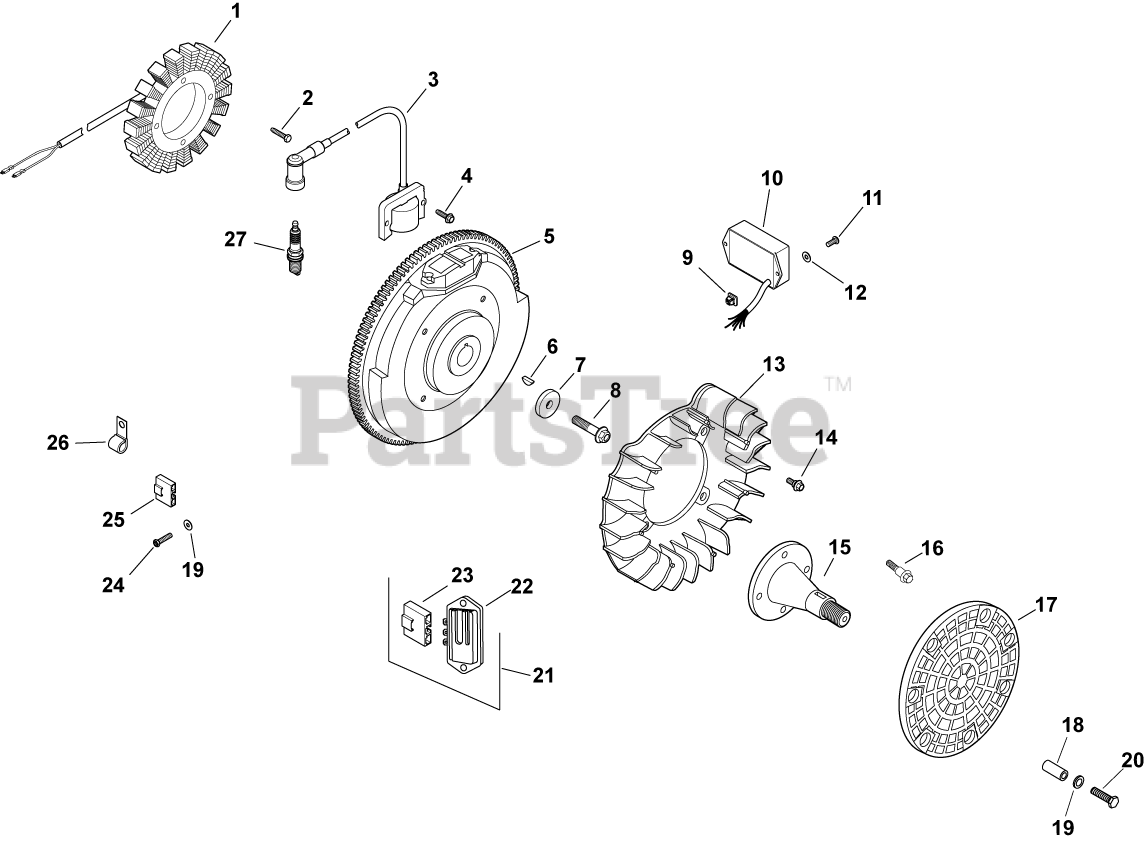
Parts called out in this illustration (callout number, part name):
1	KIT, 25 AMP STATOR ASSY.
2	SCREW, THD FROM M5X0.8X30
3	MODULE, IGNITION
4	SCREW, SKT THD FRM M5X0.8X25
5	FLYWHEEL, PAINTED-USE 24 025 57-S
6	KEY, 3/16" X 5/8"
7	WASHER, FLAT 13/32"
8	SCREW, FLG M10X1.5X45 - (#25086361S)
9	NUT, PLASTIC
10	MODULE, SPEED ADVANCE-DISCONTINUED SEE PB265
11	SCREW, PHL HD #11-16X1/2"
12	WASHER, FLAT 1/4" (O.D. 1/2")
13	FAN USE 24 157 11-S
14	BOLT, SHOULDER
15	SCREW, FLG M8X1.25X25
16	SHAFT, FRONT DRIVE
17	SCREEN, GRASS-USE 24 162 45-S
18	SPACER - DISCONTINUED
19	WASHER, FLAT 3/16"
20	SCREW, SLT HD CAP M4X0.7X25
21	KIT, FULL WAVE CONVERSION
22	REG/RECTIFIER (20/25 AMP)-USE 25 403 20-
23	CONNECTOR, BODY (KM)-USE 25 155 41-S
24	SCREW, PHL HD #11-16X7/8"
25	CONNECTOR
26	CLIP, CABLE
27	PLUG, SPARK (STD)
